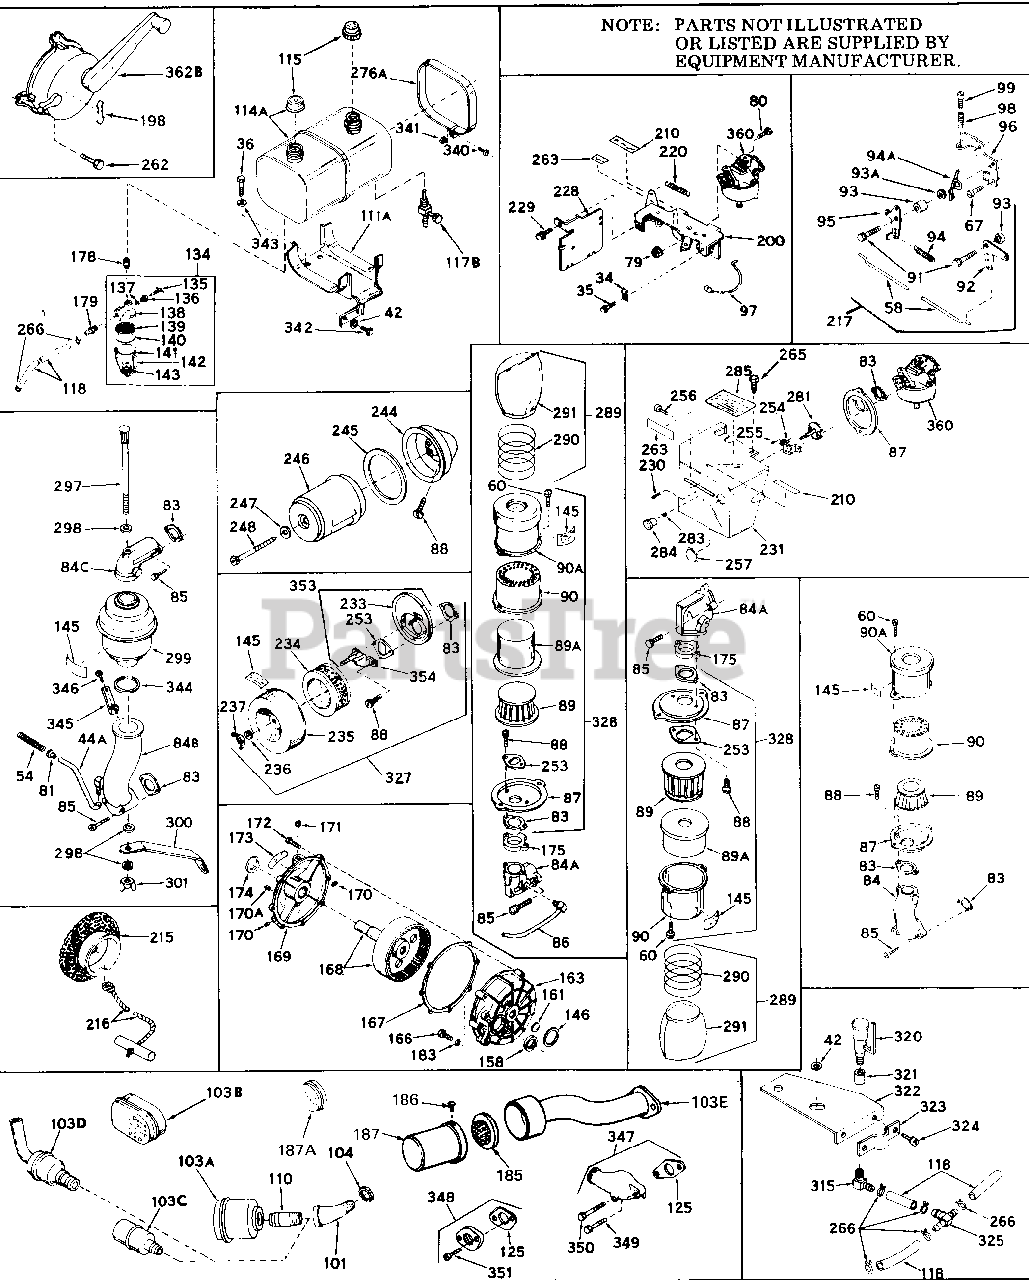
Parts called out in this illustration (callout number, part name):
34	Clip, Conduit
36	Screw, Hex hd. cap, 5/16-18 x 2 (Grad e 8
36	Screw, Hex hd. cap, 5/16-18 x 2-1/4 ( Grade 8
36	Screw, Hex hd. cap, 5/16-18 x 2-1/2 ( Grade 8
54	Spring, Breather tube
67	Screw, Fil. hex Sems. 10-32 x 5/8
79	Nut, Lock
80	Screw
83	Gasket, Air cleaner
85	Screw, Phil. fil. hd. Sems, 10-32 x 1 -5/8
88	Screw, Fil. hd. Sems, 10-32 x 5/8
88	Screw, Fil. hd. Sems, 10-32 x 1/2
98	Spring, Compression
99	Screw, Fil. hd. mach., Sems, 8-32 x 3 /4
99	Screw, Fil. slotted hd. Sems, 8-32 x 5/8
99	Screw, Hex hd. 10-32 x 1-5/16 (Drille d thru)
101	Elbow, Exhaust (45(deg))
103A	Muffler
104	Nut, Conduit (1/8" thick)
104	Nut, Conduit (1/4" thick) (Drilled th ru)
110	Nipple, Pipe (2.50")
115	Cap, Fuel filler (Plastic) (Standard)
115	Cap, Fuel filler (Plastic)
118	Line, Fuel (Braided hose) (8.25")
118	Line, Fuel (Braided hose) (16")
118	Line, Fuel (Braided hose) (32")
125	Gasket, Exhaust
145	Decal, Air cleaner
146	Gasket, Housing
171	Plug, Pipe
215	Pulley, Rope starter
216	Rope Assy., Starter
228	Baffle, Heat
233	Bracket, Air cleaner
234	Element, Air cleaner
235	Cover, Air cleaner
236	Washer, Fibre
237	Nut, Wing
253	Spacer, Cleaner
255	Screw, Fit. hd. Sems, 10-32 x 1/2
256	Screw, Phil. Pan hd. thread forming 8 -32 x
257	Plug, Cover
265	Screw, Hex washer hd., 8-18 x 7/16
266	Clamp, Fuel line
289	Kit, Pre-cleaner
290	Spring, Pre-cleaner bag
291	Bag, Pre-cleaner
327	Cleaner Assy., Air
328	Cleaner Assy., Air
342	Screw
347	Kit, exhaust adapter
348	Kit, Exhaust adapter
349	Screw
350	Screw, Hex hd. cap, 5/16-18 x 2-1/2 ( Grade 8
351	Screw
353	Bracket Kit, Air cleaner
354	Bracket, Air cleaner
360	Carburetor
